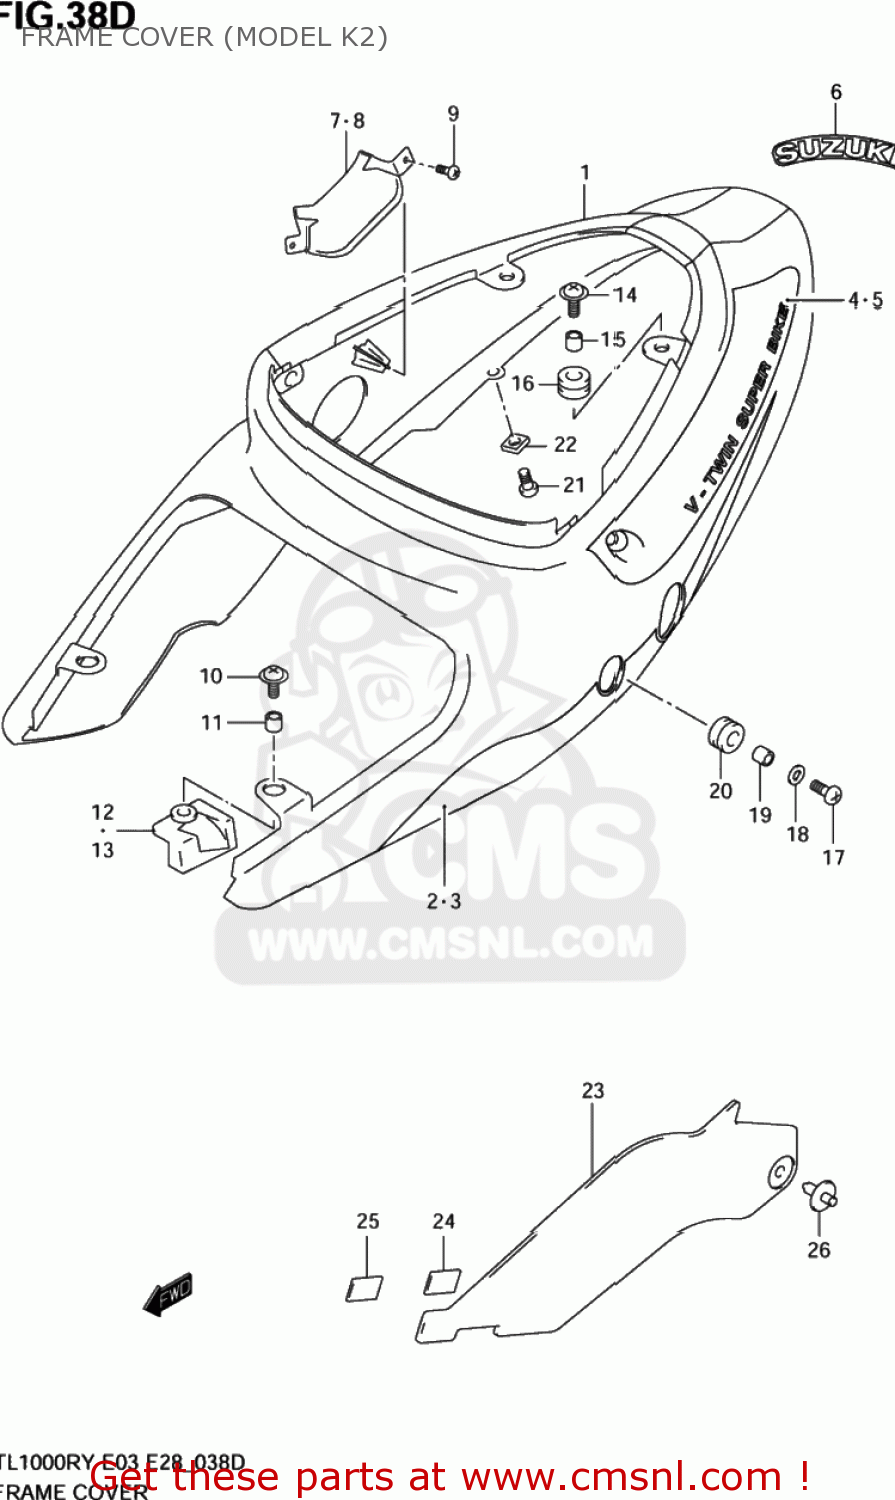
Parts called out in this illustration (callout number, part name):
1	COVER,FRAME(BLACK)
2	TAPE SET,FRAME COVER,R
3	TAPE SET,FRAME COVER,L
4	TAPE,FRAME COVER,R
5	TAPE,FRAME COVER,L
6	EMBLEM,FRAME COVER
7	CAP,FRAME COVER HOLE,R
8	CAP,FRAME COVER HOLE,L
9	SCREW
10	SCREW(6X20)
11	SPACER(6.5X9X9)
12	CUSHION,FRAME COVER,R
13	CUSHION,FRAME COVER,L
14	SCREW(6X20)
15	SPACER(6.5X10X9.4)
16	CUSHION
17	SCREW(6X20)
18	WASHER(6.5X22X1.6)
19	SPACER(6.5X9X6.7)
20	CUSHION
21	CLIP
22	NUT
23	COVER,FRAME,FRONT,RIGHT
24	FASTENER,NO.1
25	FASTENER,NO.2
26	CLIP(GRAY)
